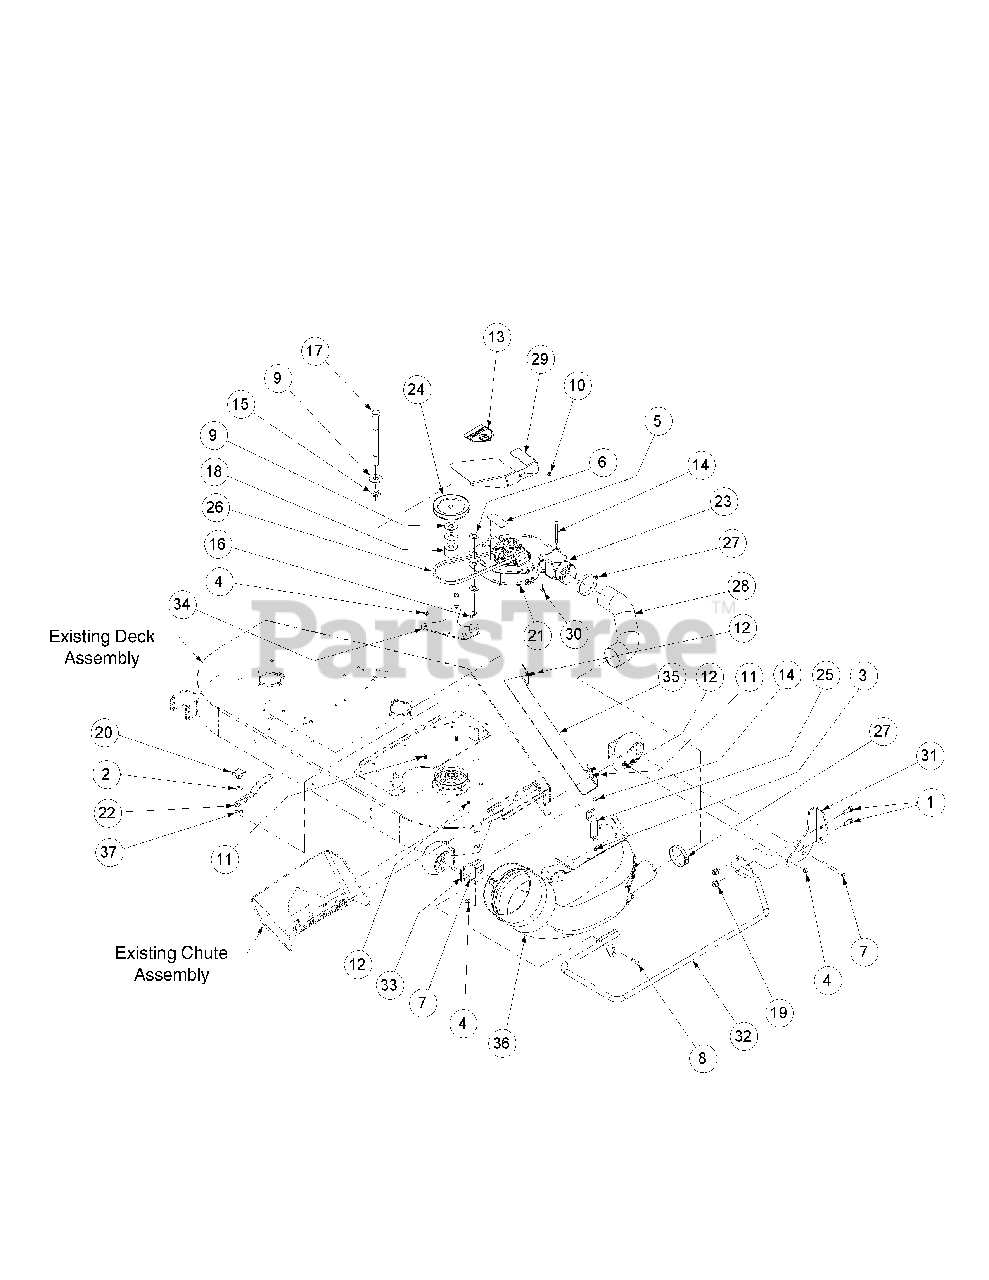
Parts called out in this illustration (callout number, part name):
1	HHCS, 1/2-13 x 1.25
2	Flat Washer, 3/8
3	Hex Cap Screw, 1/4-20, .75
4	Hex Nut Flange Lock, 3/8-16
5	Decal, Warning Shield Missing
6	Flat Washer, .76 x 1.49 x .06
7	HHCS, 3/8-16 x 4.50
8	HHCS, 3/8-16 x .88
9	Flat Washer, .781 ID x 2.00 OD x .105
10	Screw, TT, 1/4-20, 0.5, Hex Index Washer
11	Carriage Bolt, 3/8-16 x 1
12	Carriage Screw, 3/8-16 x 1.25
13	Decal, Danger Hands & Feet
14	Lock Nut, 1/4-20
15	Spacer, .812 ID x .268 Lg.
16	Cotter Pin, .148 x 3.00
17	Hex Cap Screw, 3/4-16, 9.00
18	Spacer, .76 OD x 2.00 OD x 1.39
19	Nut, 1/2-13, Flange Lock
20	Plastic Knob
21	Blower Assembly
22	Tension Assembly
23	Adaptor Tube
24	Pulley, V-Type 5.5 Dia.
25	Chute Stop Deflector Bracket
27	Hose Clamp, 3.00 Dia.
28	Hose Duct
29	Deck Blower Deflector Cover
30	HHCS, 1/4-20 x 3.50
31	MCS Guard Plate
32	MCS Guard Weldment
33	MCS Guard Adaptor
34	Pivot Weldment
35	Baffle Bracket
36	Chute Elbow Assembly
37	Push Retainer
